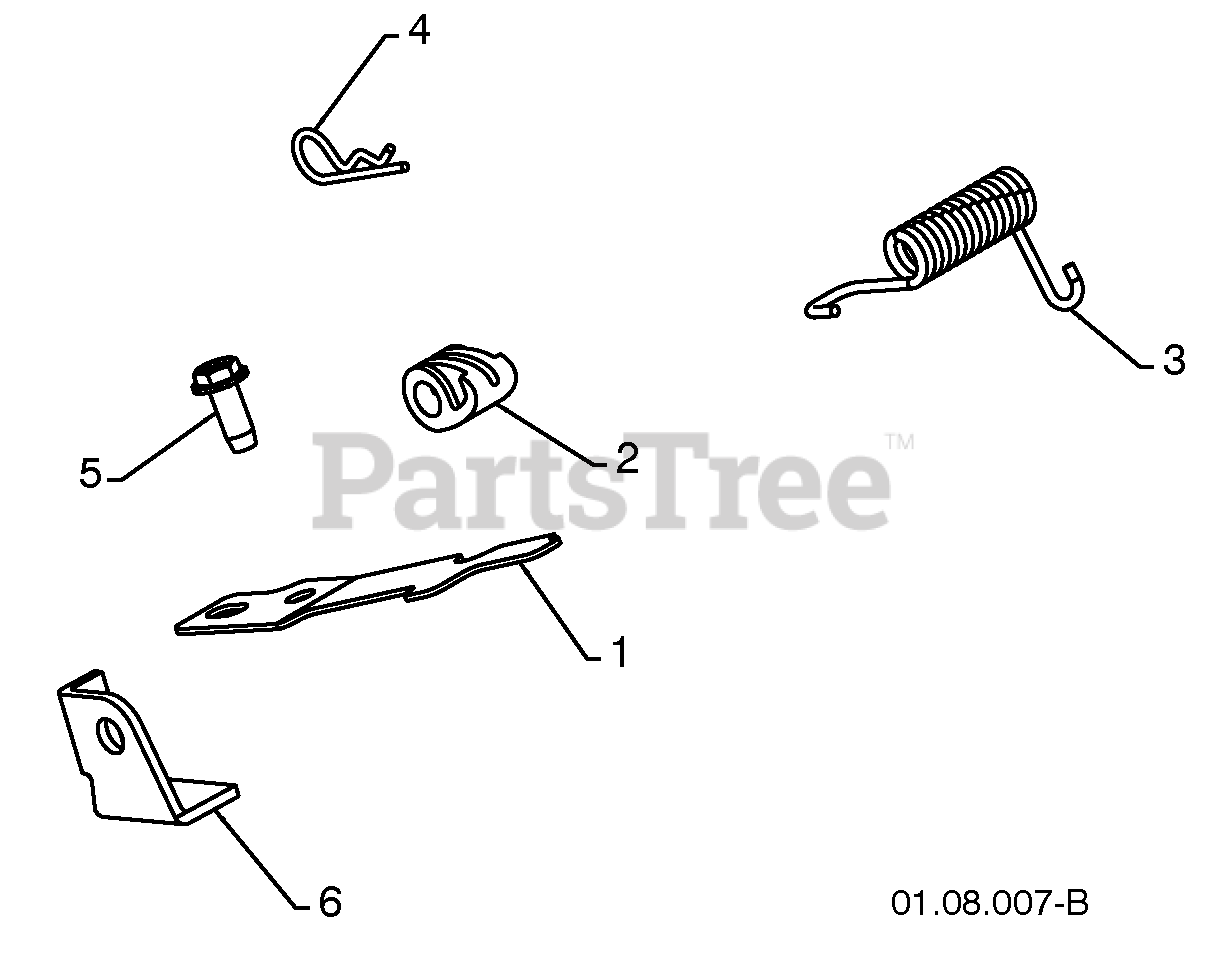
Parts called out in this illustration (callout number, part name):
1	INTERLOCK SPRING
2	INTERLOCK CAM
3	TORSION SPRING
4	RETAINER
5	SCREW 1/4-20 X .625
6	INTERLOCK STOP
